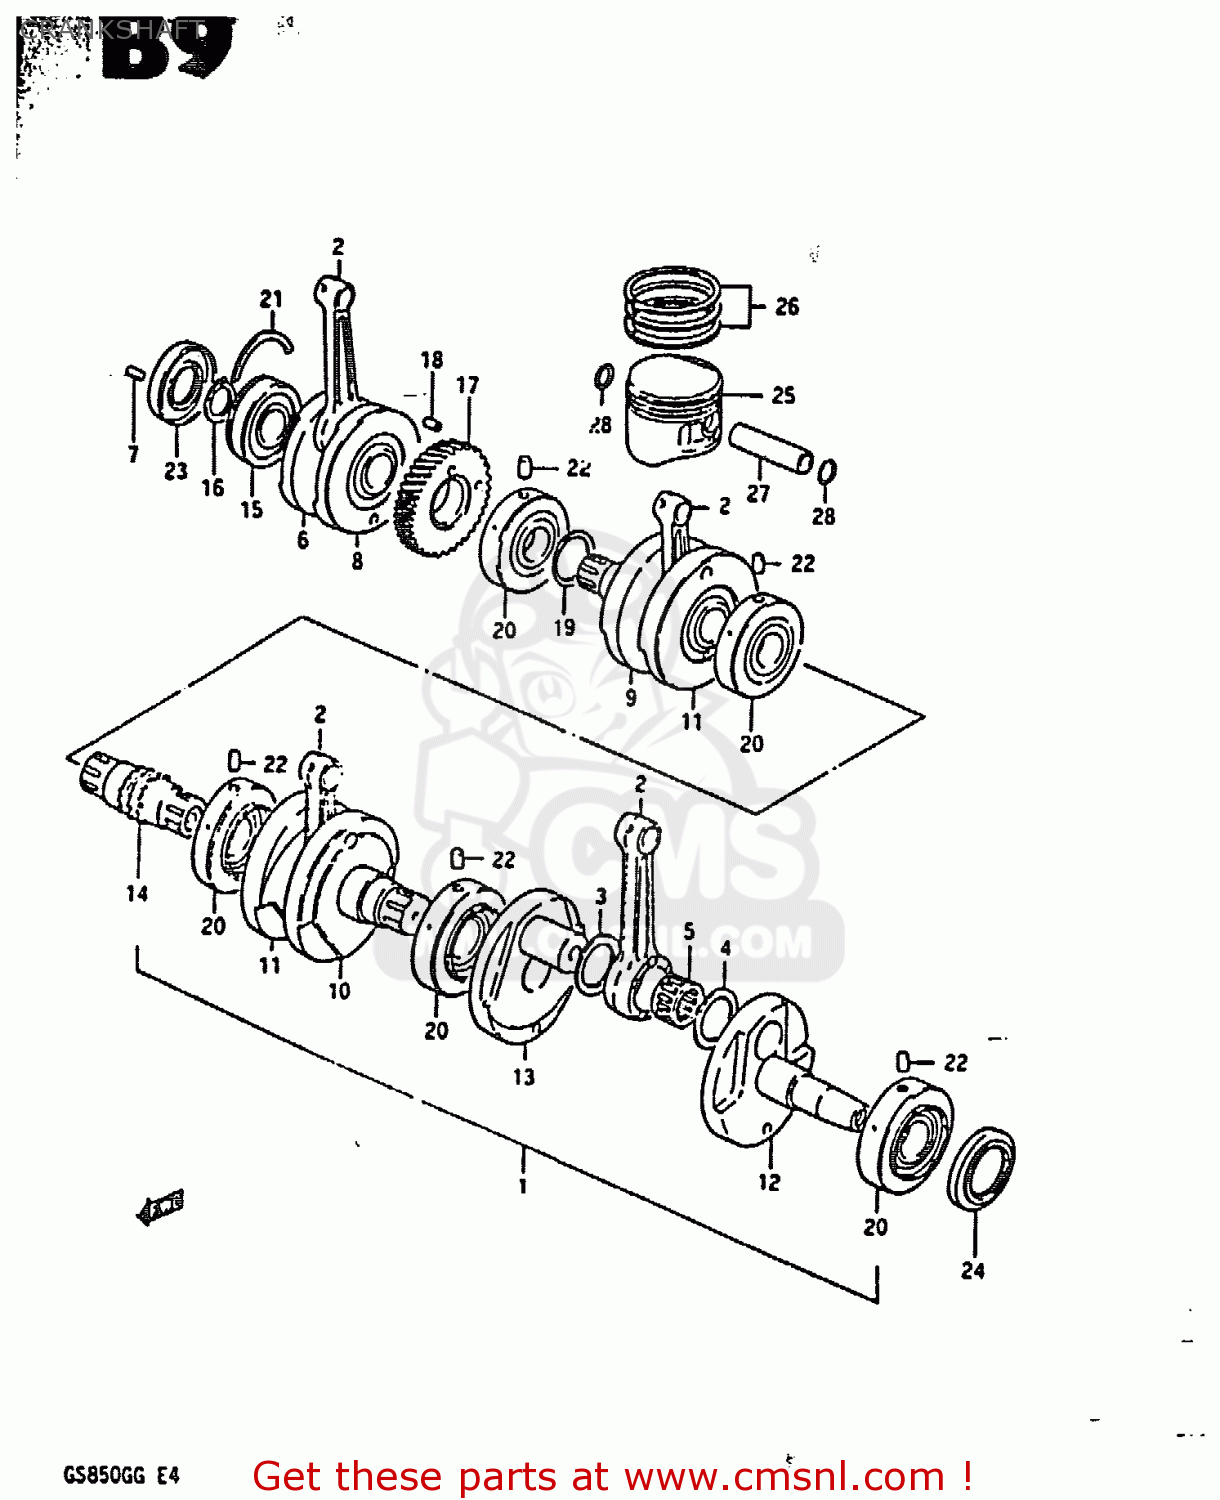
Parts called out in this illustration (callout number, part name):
1	CRANKSHAFT ASSEMBLY
2	ROD,CONNECTING
3	WASHER (29X48X2)
4	WASHER (29X48X1)
5	BEARING(29X39X20)
6	CRANKSHAFT
7	PIN
8	WEB,CRANK,RIGHT
9	CRANKSHAFT
10	CRANKSHAFT, MIDDLE LH
11	WEB,CRANK,MIDDLE
12	CRANKSHAFT,LEFT
13	WEB,CRANK,LEFT
14	SHAFT,TIMING CHAIN DRIVE
15	BEARING(30X72X19)
16	CIRCLIP,30MM
17	GEAR,PRIMARY DRIVE
18	PIN
19	WASHER
20	BEARING(32X72X21)
21	C RING
22	PIN
23	SEAL,OIL(30X72X11)
24	OIL SEAL
25	PISTON
26	RING SET,PISTON
27	PIN,PISTON
28	CIRCLIP
